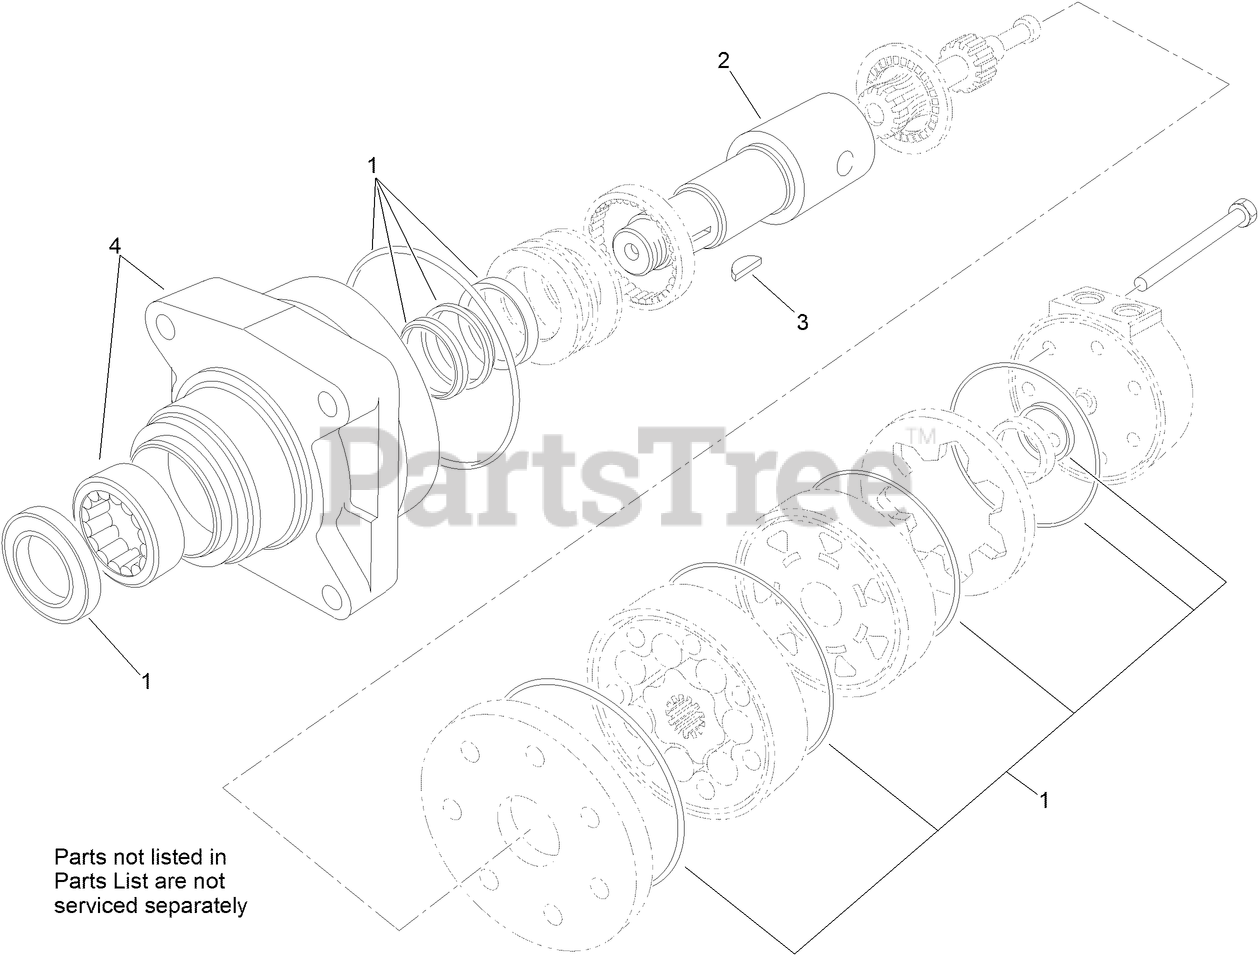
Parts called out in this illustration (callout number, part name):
1	SEAL KIT
2	COUPLING-SHAFT
3	KEY-WOODRUFF
4	MOTOR HOUSING ASM
